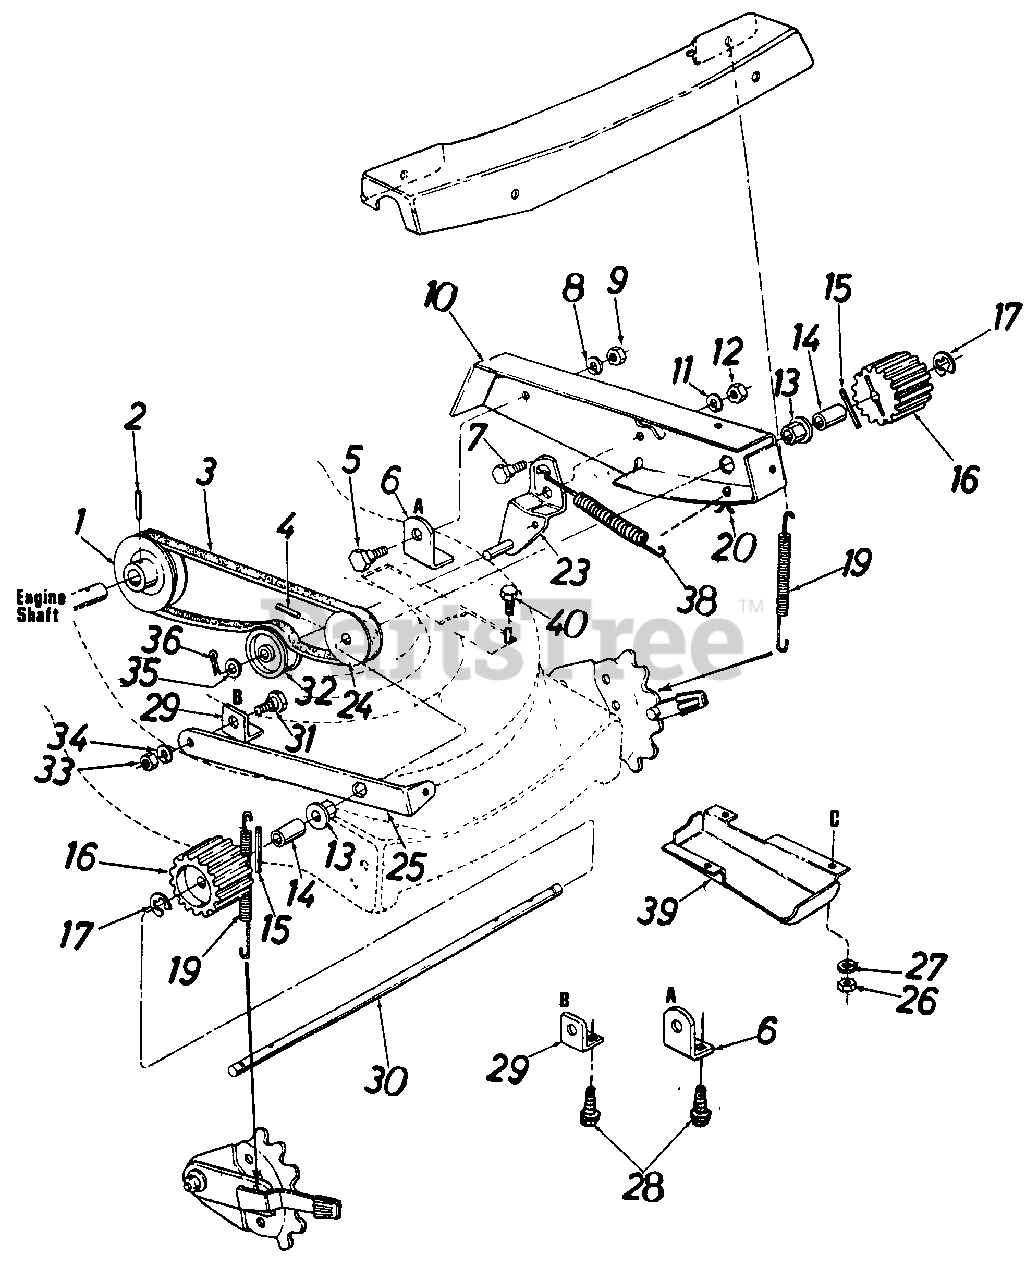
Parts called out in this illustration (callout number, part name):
1	1/2 "V"-Engine Pulley
2	Spring Pin Spiral 3/16" Dia. x 1.25" Lg.
3	"V"-Belt 1/2" x 28.0" Lg.
4	Spring Pin Spiral 3/16" Dia. x 1.00" Lg.
5	Shld. Bolt .500 Dia. x .170
6	Belt Cover Pivot Brkt.
7	Shld. Bolt .500 Dia. x .170
8	L-Wash. 3/8" I.D.
9	Hex Jam Nut 3/8-16 Thd.
10	Belt Cover Ass'y.
11	L-Wash. 3/8" I.D.
12	Hex Jam Nut 3/8-16 Thd.
13	Hex Flange Brg. .503 I.D.
14	Spacer .52 I.D. x .69 O.D. x .88
15	Spring Pin Spiral 3/16 Dia. x 1.25" Lg.
16	13 Teeth Drive Pinion
17	"E"-Ring for .500 Dia. Shaft
19	Extension Spring .40 O.D. x 3.00" Lg.
20	Cotter Pin
23	Idler Brkt. Ass 'y.
24	1/2 "V"-Pulley
25	Cover Support Brkt.
26	Hex Nut 1/4-20 Thd.
27	L-Wash. 1/4" I.D.
28	Hex Wash. Hd. Self-Tap Scr. 1/4-20 x .50" Lg.
29	Cover Support Pivot Brkt.
30	Pinion Shaft
31	Shld. Bolt .500 Dia. x .170
32	Plastic Flat Idler
33	Hex Jam Nut 3/8-16 Thd.
34	L-Wash. 3/8" I.D.
35	Fl-Wash. .53 I.D. x .93 O.D.
36	Cotter Pin 1/8" Dia. x 1.00" Lg.*
38	Extension Spring
39	Belt Cover Baffle
40	Truss Mach. Scr. 1/4-20 x .50" Lg.
